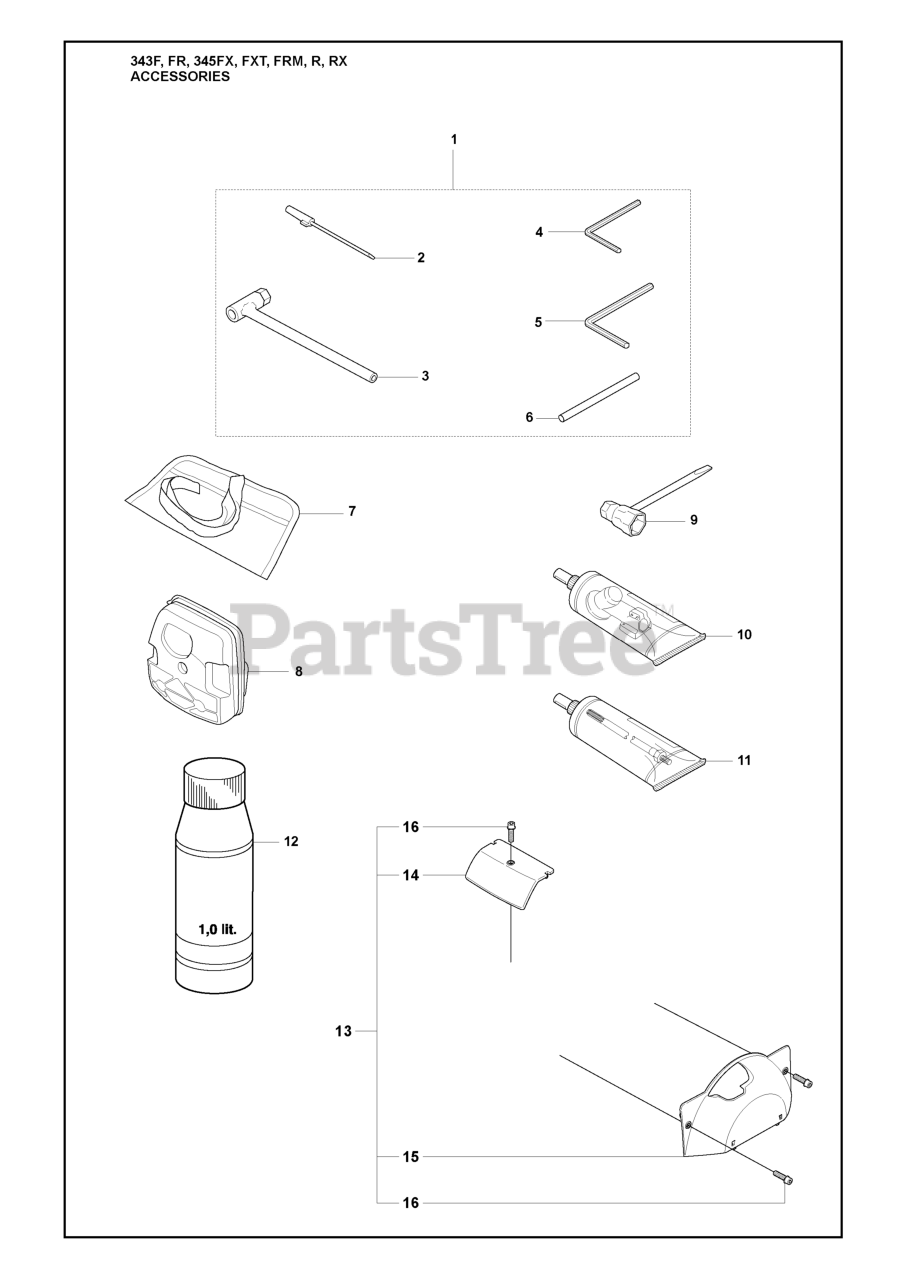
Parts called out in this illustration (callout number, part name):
1	TOOL KIT
2	SCREWDRIVER
4	L-KEY WRENCH
5	L-SPANNER
6	LOCKING PIN
8	AIR FILTER
8	FILTER
9	COMBI TOOL
10	BEVEL GEAR GREASE
11	DRIVE SHAFT GREASE (200 G)
12	Air Filter Oil, HVA 1L Bottle
13	WINTER SET
